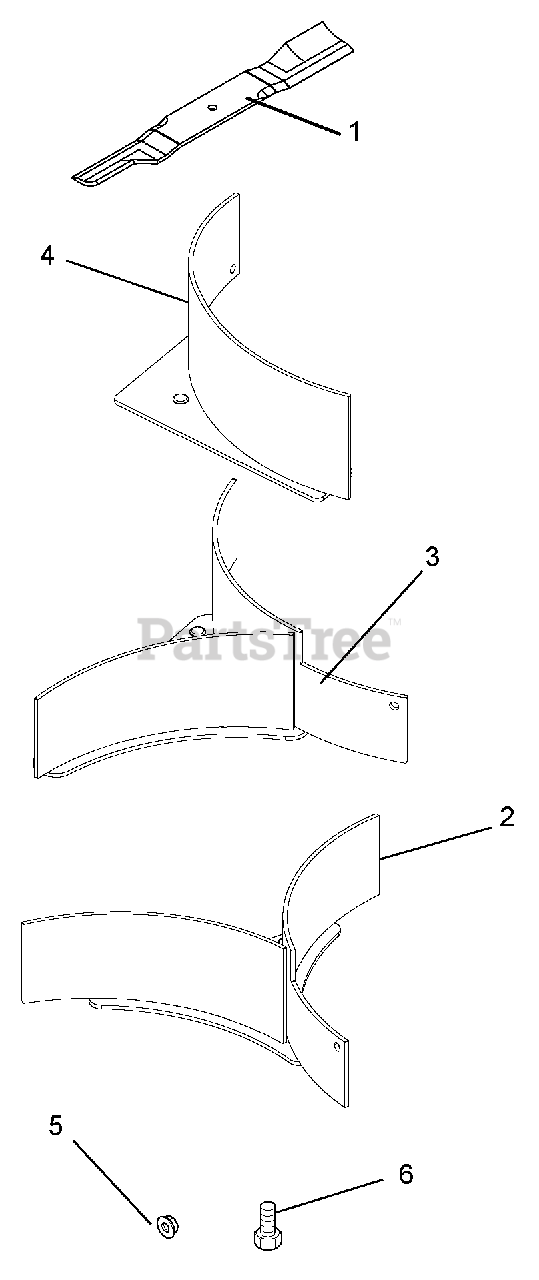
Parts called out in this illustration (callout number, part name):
1	44" and 48" Mulch Blade 16.25
2	44" and 48" Left Mulch Baffle
3	44" and 48" Right Mulch Baffle
4	44" Discharge Mulch Baffle
4	48" Discharge Mulch Baffle
5	.31-18 Nyloc Flange Nut
6	.31-18 x 1.00 Hex Bolt
